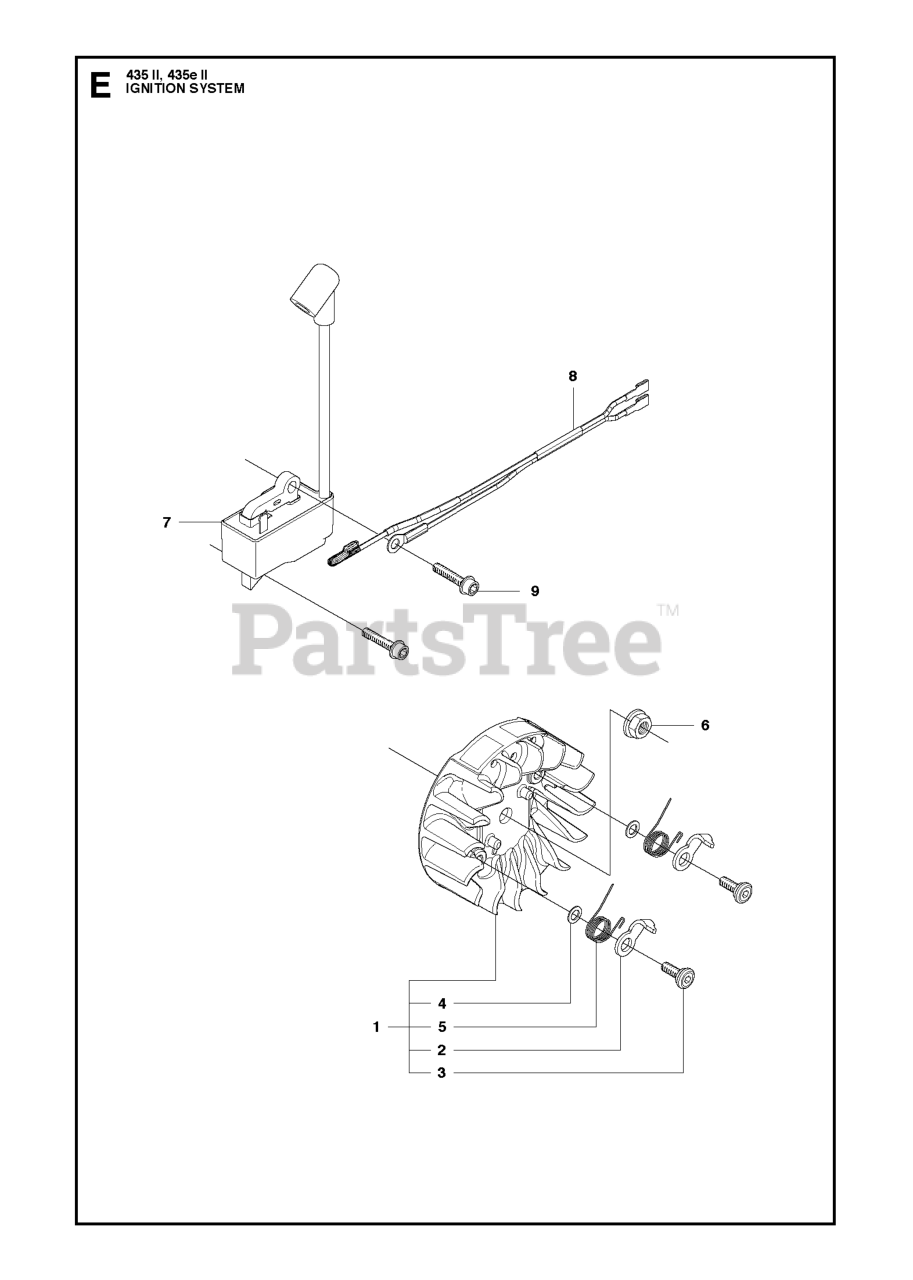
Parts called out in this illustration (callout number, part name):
1	FLYWHEEL ASSY D90
6	NUT W/ WASHER
7	IGNITION MODULE MBU-52A/HDS1.1
8	WIRING ASSY
